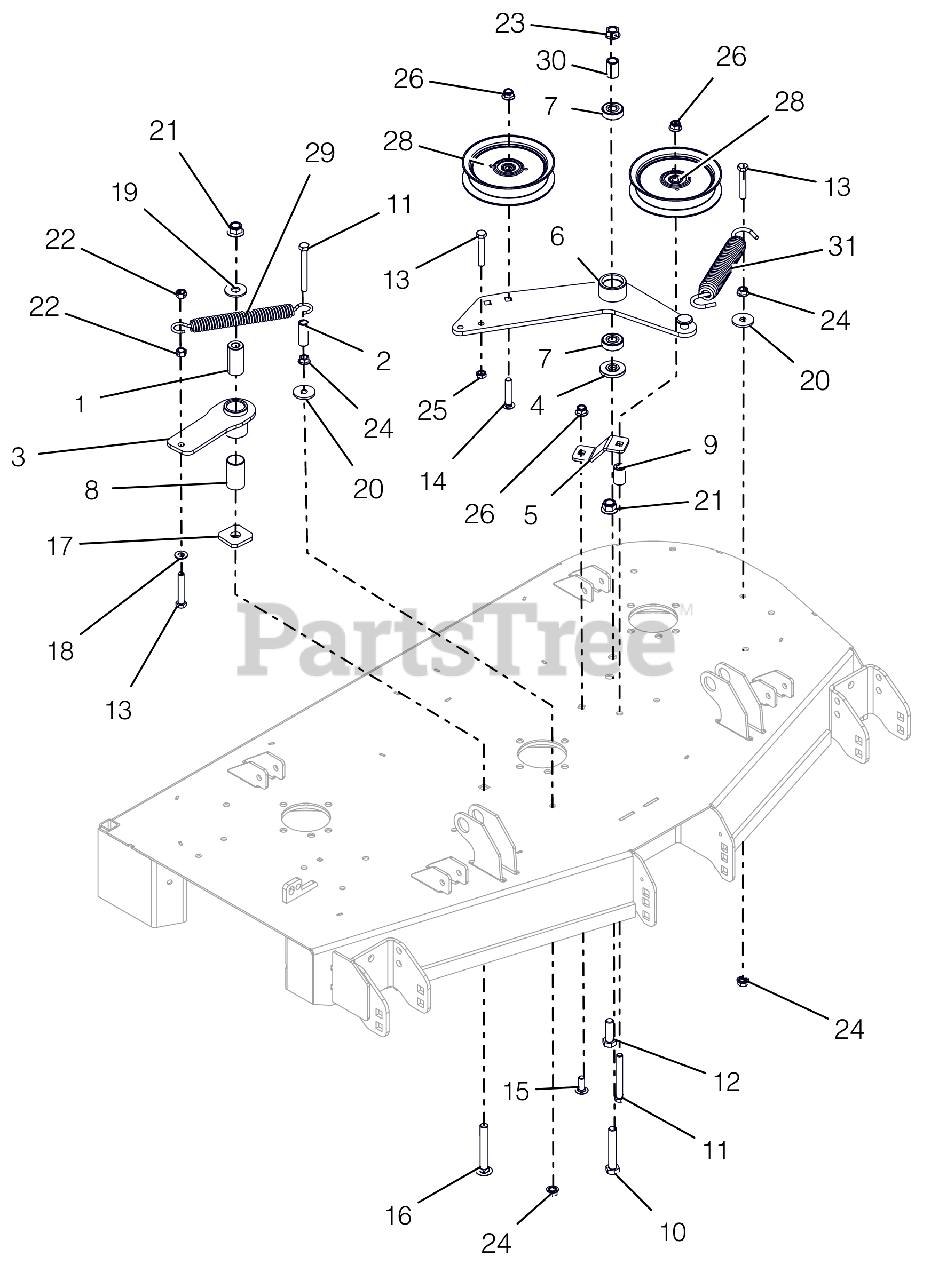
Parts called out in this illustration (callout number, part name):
1	BSHG, SPCR .502X.997X2.03 PM
2	SPACER, .375IDX.625ODX1.66 PM
3	WMT, IDLER ARM - BLACK
4	SPACER, IDLER ARM
5	PTO FIXED IDLER MTG BRKT -RED
6	DECK PTO IDLER ARM WLDMT - BLK
7	BRG-BALL .500X1.38X.437
8	BSHG, 1.00X1.125X1.937
9	BUSHING, SLV .380X.750X1.190
10	@BLT-HEX .50-13X3.00 GR5 YWZC
11	@BLT-HEX .38-16X3.25 GR5 YWZC
12	@BLT-HEX .50-13X1.50 GR5 YWZC
13	@BLT-HEX .38-16X2.25 GR5 YWZC
14	BLT-RDHDSQNK .38-16X2.00 SHTYW
15	@BLT-RDHDSHSQNK.38-16X1.0 G5YZ
16	@BLT-RDHDSQNK .50-13X3.50 G5YZ
17	WSHR-FLT .640X1.75X.250
18	@WSHR-FL-STL.406X.812X.065 YWZ
19	@WSHR-FL-STL.563X1.38X.109YWZC
20	WSHR-FL-STL .406X1.375X.135 YZ
21	@NUT-LK-NYL-FLG .50-13 YWZC
22	@NUT-LK-CTR .38-16 YWZC
23	NUT-LK-CTR-FLG .50-13 YWZC
24	@NUT-SPNLK-FLG .375-16 YWZC
25	NUT-HEX-JAM .375-16 YWZC
26	@NUT-LK-NYL-FLG .38-16 YWZC
28	IDLER, FLAT 5.00"
29	SPRING, EXTENSION
30	SPACER .510 X .75 X 1.1485
31	SPRING, EXTENSION
